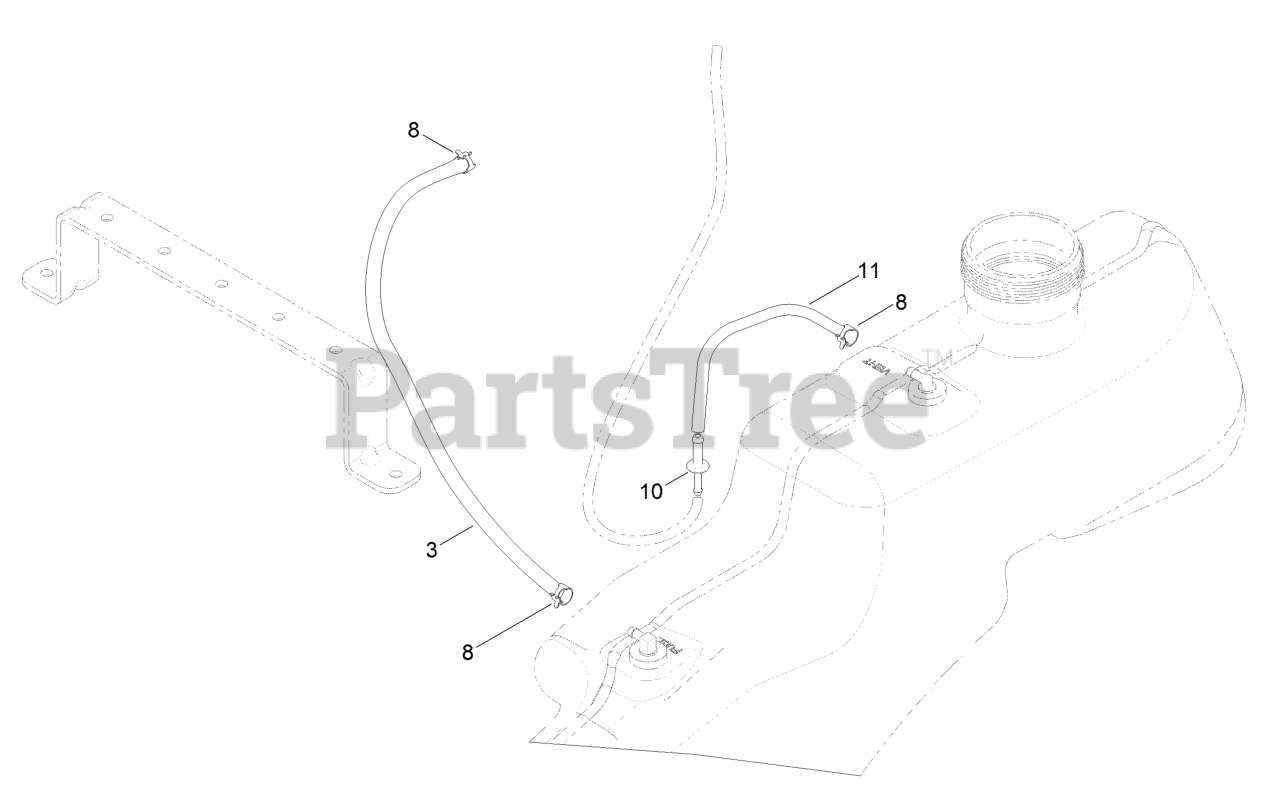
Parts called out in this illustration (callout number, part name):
3	HOSE-FUEL
8	CLAMP-HOSE
10	ADAPTOR-ORIFICE
11	HOSE-FUEL
